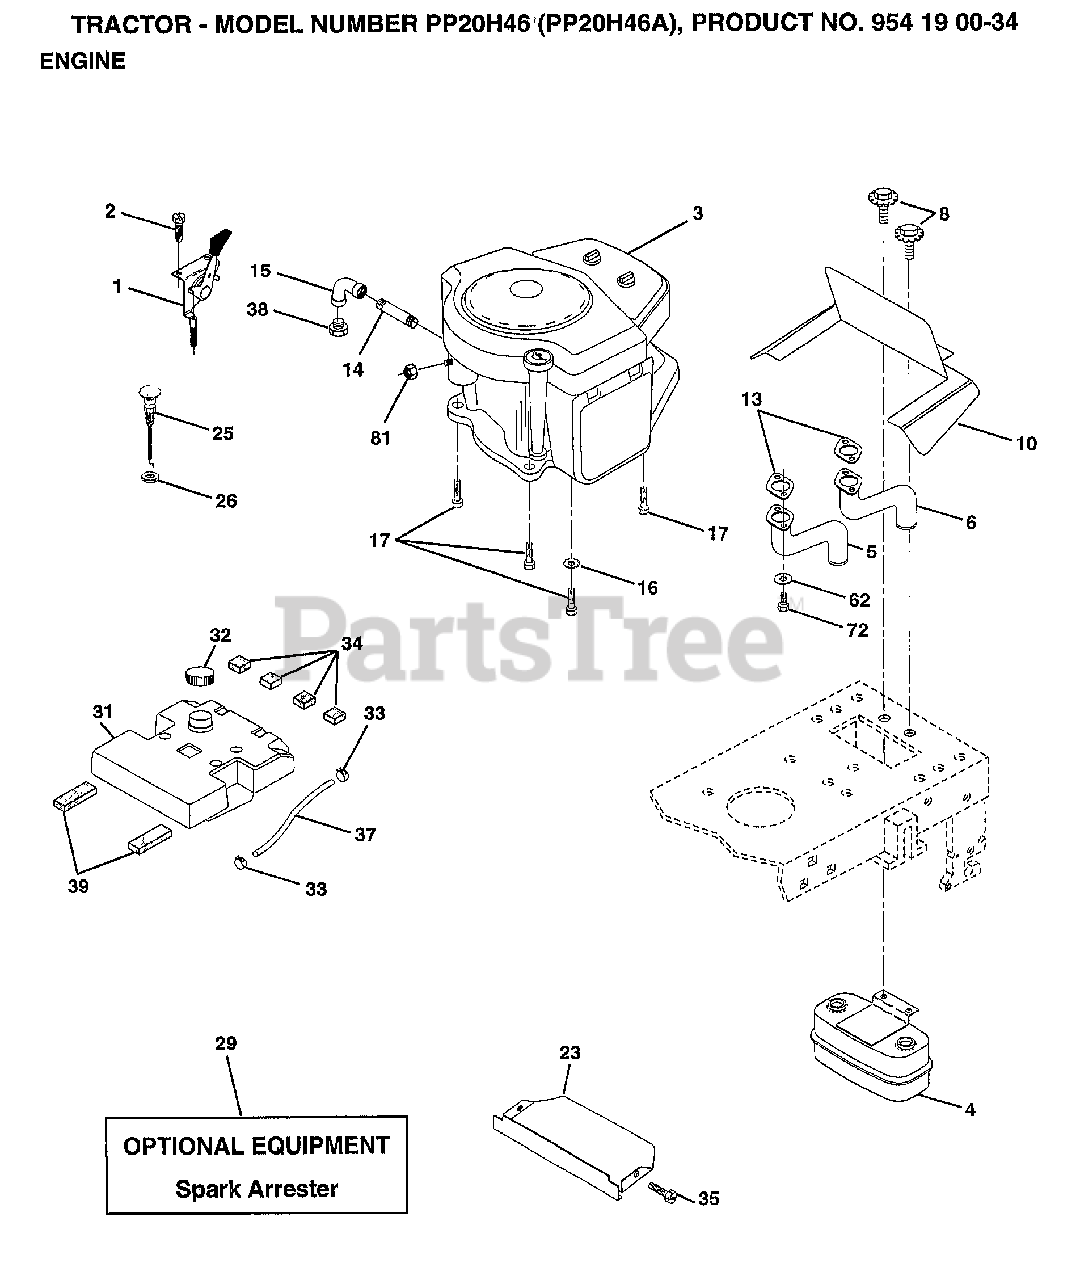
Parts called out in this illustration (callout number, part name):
1	CONTROL THROT. LH
2	SCREW LT
4	MUFFLER.TW.LOTONE
5	TUBE MANIFOLD LH
6	TUBE MANIFOLD RH
8	BOLT.5/16-18.UNC
10	SHIELD.BROWNING
11	LOCKWASHER
12	SCREW
14	PIPE NIPPLE LT
15	ELBOW
16	LOCKWASHER
17	SCREW LT
23	SHIELD.BRN/DBR.GD
25	CONTROL.CHOKE.37
26	"NUT,KEPS 3/8-24IM"
31	"TANK.FUEL,3.5 GAL"
32	CAP ASM FUEL
33	HOSE CLAMP
34	PAD-SPACER LT
35	SCREW
37	FUEL LINE T
39	PAD IDLER TI
81	NUT
101	NUT FLANGE M8-125
